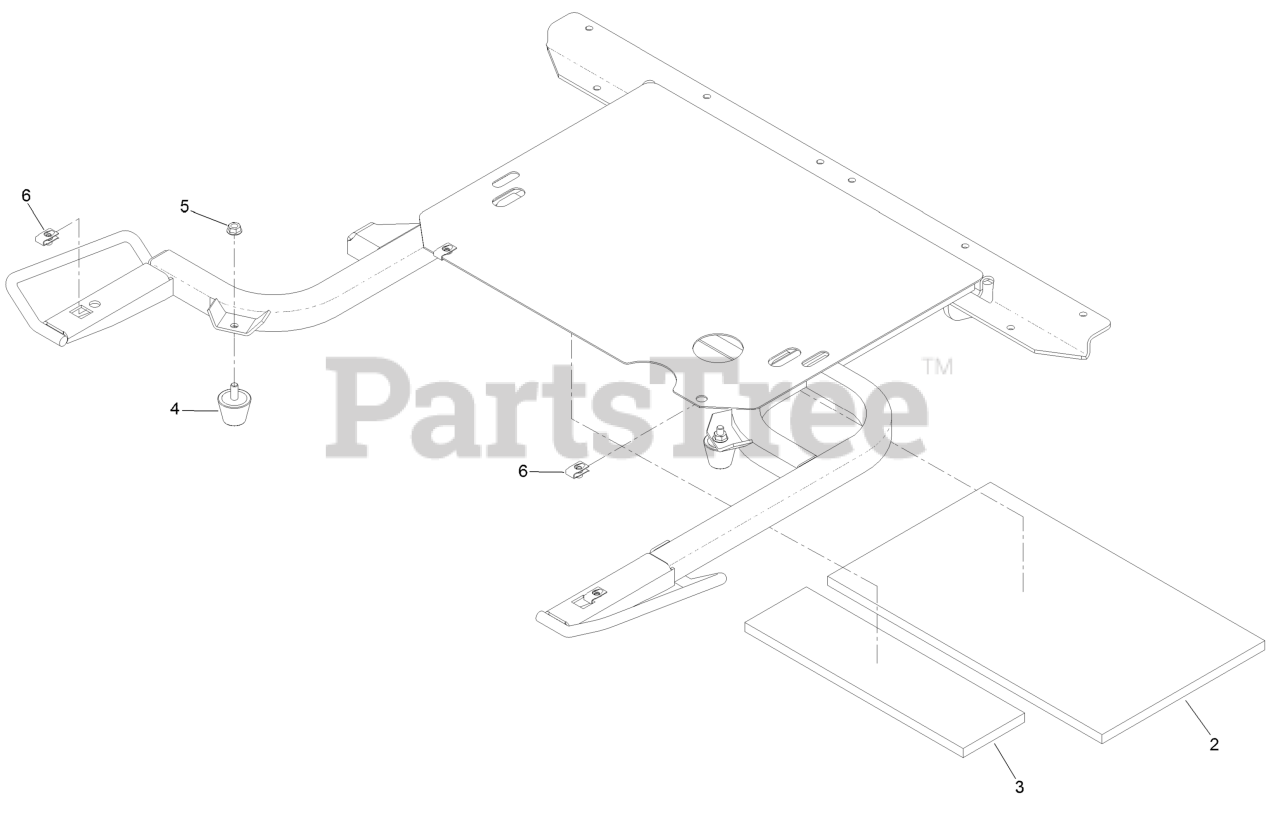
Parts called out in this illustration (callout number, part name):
2	INSULATION-FOAM PAD, REAR
3	INSULATION-FOAM PAD, FRON
4	BUMPER-RUBBER
